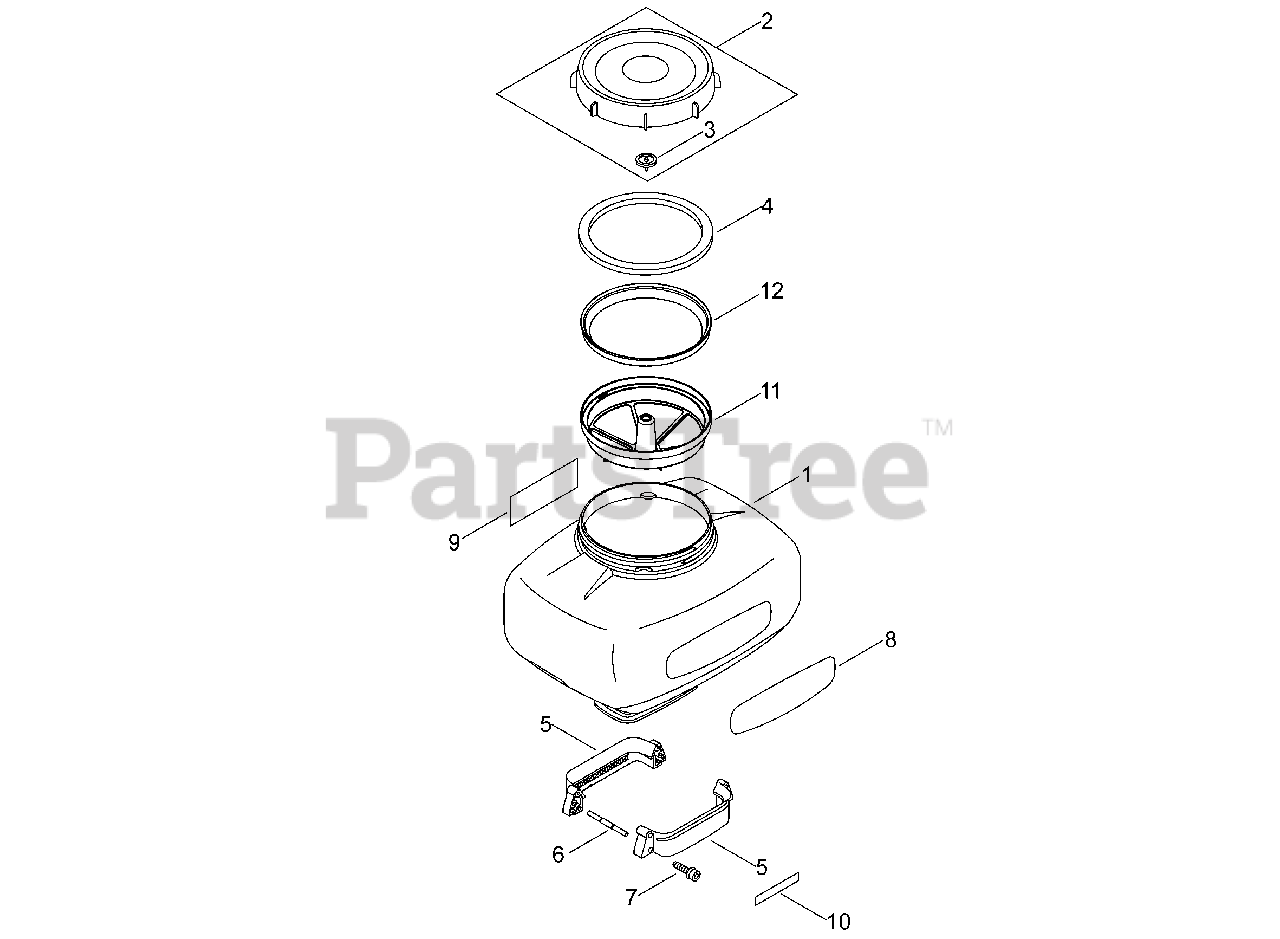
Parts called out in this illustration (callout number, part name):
1	TANK, CHEMICAL 23L
2	CAP ASSY, CHEMICAL TANK
3	CONNECTOR, PIPE
4	GASKET, CAP
5	BRACKET
6	PIN, LOCATING
7	SCREW, TAPPING HS M5×35
8	LABEL, ECHO
9	LABEL, CAUTION - ISO
10	LABEL, MODEL MB-580
11	FILTER, TANK
12	FILTER, TANK
